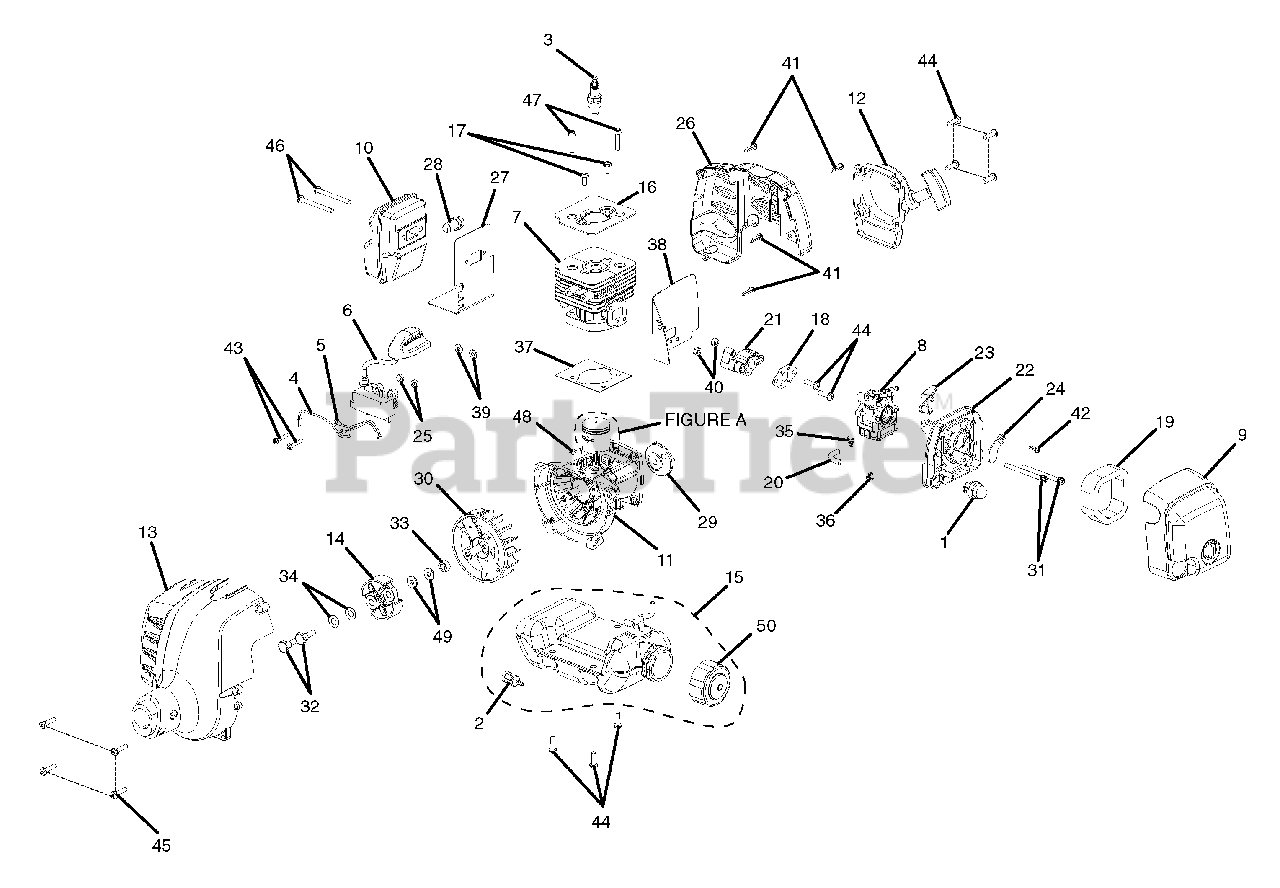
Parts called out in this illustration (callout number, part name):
1	Primer Assembly
2	Fuel Filter
3	Spark Plug
4	Lead Assembly,Black
5	Lead Assembly,Red
6	Coil, Boot,Assembly
7	Cylinder
8	Carburetor Assembly
9	Cover Assembly
10	Muffler Assembly
11	Crankcase Assembly
12	Starter Recoil Assembly
13	Front Housing Assembly
14	Clutch Assembly
15	Fuel Tank Assembly
16	Cylinder Plate
17	Screw,(M5x0.8x10in.Torx Recessed Pan Head,
18	Carburetor Gasket
20	Tubing, Plastic Rubber
21	Insulator, Heat Dam
22	Carburetor Plate
23	Choke Lever
24	Choke Plate
25	Ignition Coil Spacer
26	Engine Housing, Rear
27	Muffler Gasket
28	Spark Arrester
30	Rotor, Permanent Magnet
31	Screw (M5 x 0.8 x Slotted Recessed Pan Machine)
32	Clutch Screw
33	Rotor Nut
34	Curved Washer
35	Hose Clip
36	Hose Clip
38	Insulator Gasket
39	Type A, Plain Washer (3/16 x 7/16 x 3/64,
40	Nut,(M5 x .8 mm)Black Oxide
41	Screw (M4x1.75x16 mm, Type TT, Slotted Recessed Pan)
42	Screw (M4 x 1.75 x Type TT, Slotted Pan HD.)
43	Screw (M4 x 0.7 x Torx Recessed Pan Machine)
44	Screw (M5 x 0.8 x Torx Recessed Pan Machine)
45	Screw (M5 x 0.8 x Torx Recessed Pan Machine)
46	Screw (M5 x 0.8 x Torx Recessed Pan Machine)
47	Screw (M5 x 0.8 x Socket Head Cap, Black Oxide)
48	Woodruff Key(10 mmx3.7 mmx3mm)
50	Fuel Cap
